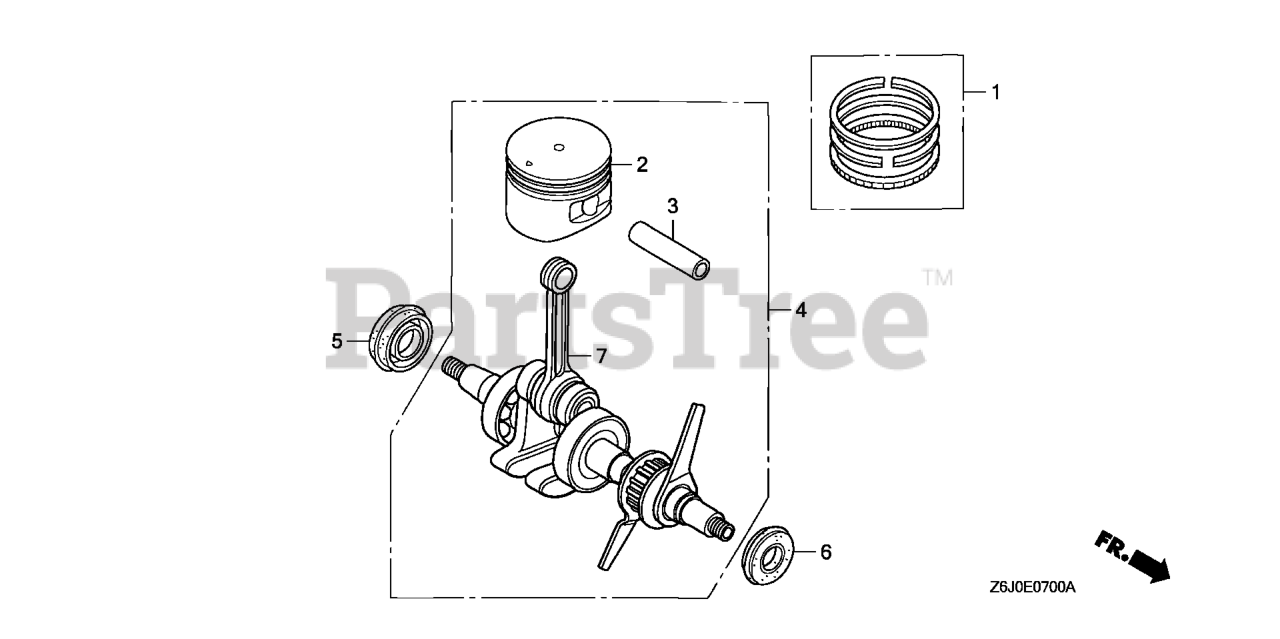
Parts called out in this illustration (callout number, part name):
1	RING SET, PISTON
1	RING SET, PISTON (TPR)
2	PISTON (STD)
3	PIN, PISTON
4	CRANKSHAFT
5	OIL SEAL (12X24X5)
6	OIL SEAL (10X20X5)
7	CRANKSHAFT
